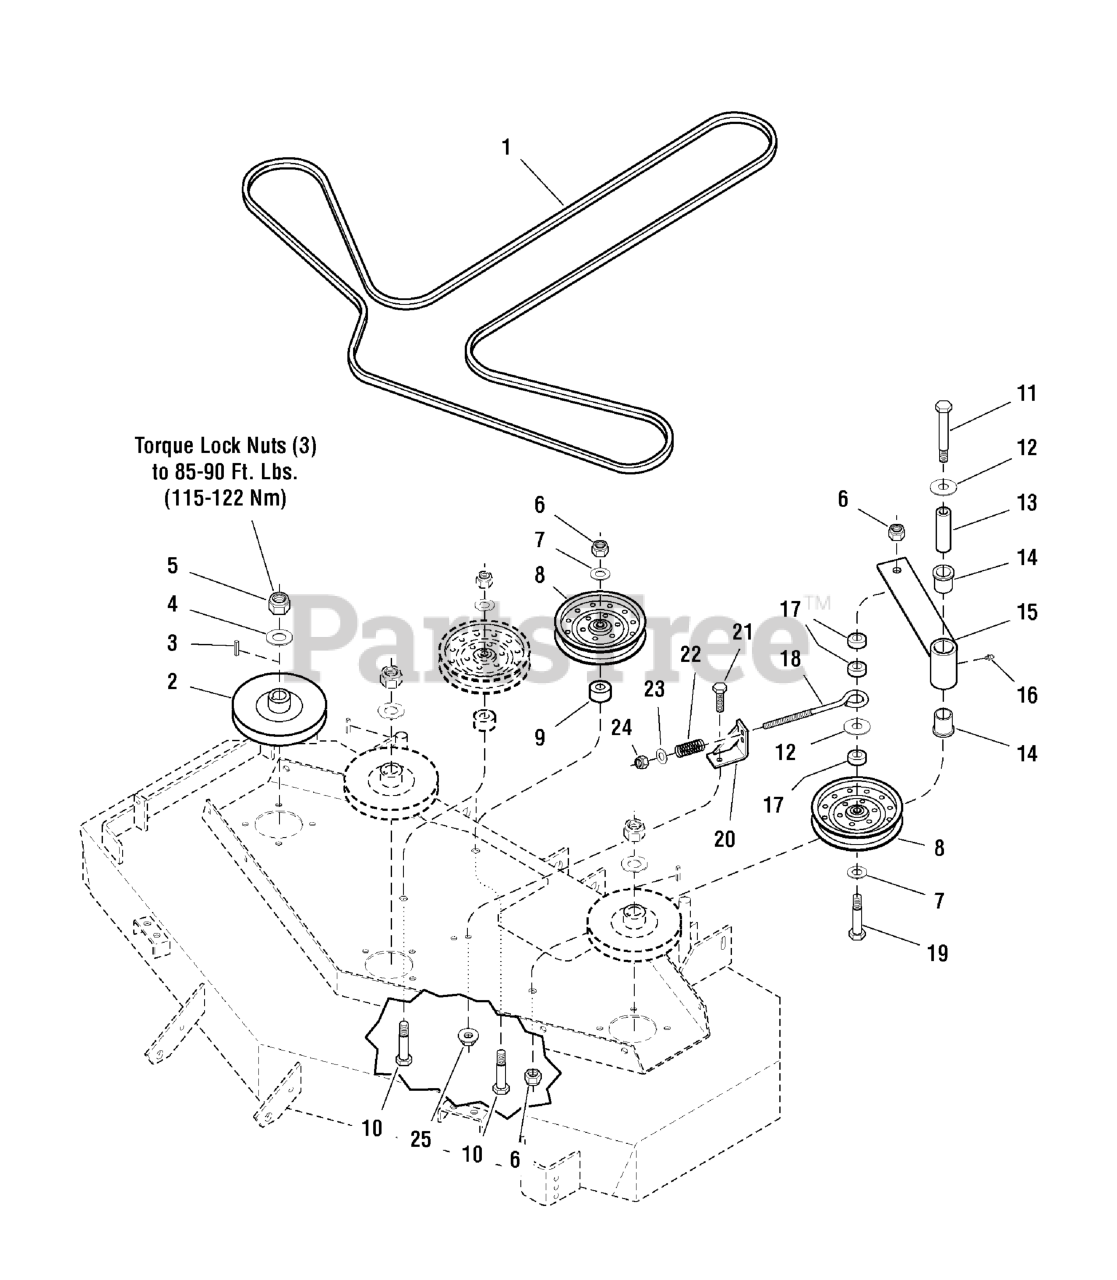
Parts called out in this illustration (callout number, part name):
1	BELT (48" Deck)
1	BELT, 5V, 150.90"EL, ARAMID, WRPD, RC
2	PULLEY, Spindle, Gold
2	PULLEY, 5.540OB X .985ID, SINGLE B-SEC
2	PULLEY, 6.122 OD X .98 BORE
3	KEY, 1/4 SQ. X 1-1/4
4	WASHER, Spring
5	NUT, 5/8-18 Hex Nylon Lock
6	NUT, 1/2-13 HEX NYLON LOCK
7	WASHER, 1/2 SAE
9	SPACER, .52 x 1.25 x .70
10	BOLT, 1/2-13 X 3" GD5 CZ
11	BOLT, 1/2-13 x 4-1/2
12	WASHER, 1/2" USS
13	SPACER, .52 x 1.00 x 3.50
14	BUSHING, FLANGE
15	ASSM, IDLER ARM
16	GREASE FITTING
17	SPACER, .52 x 1.00 x .44
18	EYEBOLT, 3/8" x 8"
19	BOLT, 1/2-13 X 3-1/2, HEX HD, GD5, CZ (SV)
20	SPRING ANCHOR
21	BOLT, 3/8-16 X 1" GD5 CZ
22	SPRING, Compression
23	WASHER, 3/8 SAE
24	NUT, 3/8-16 HEX NYLON LOCK
25	NUT, 3/8-16 Hex Serrated Flange
